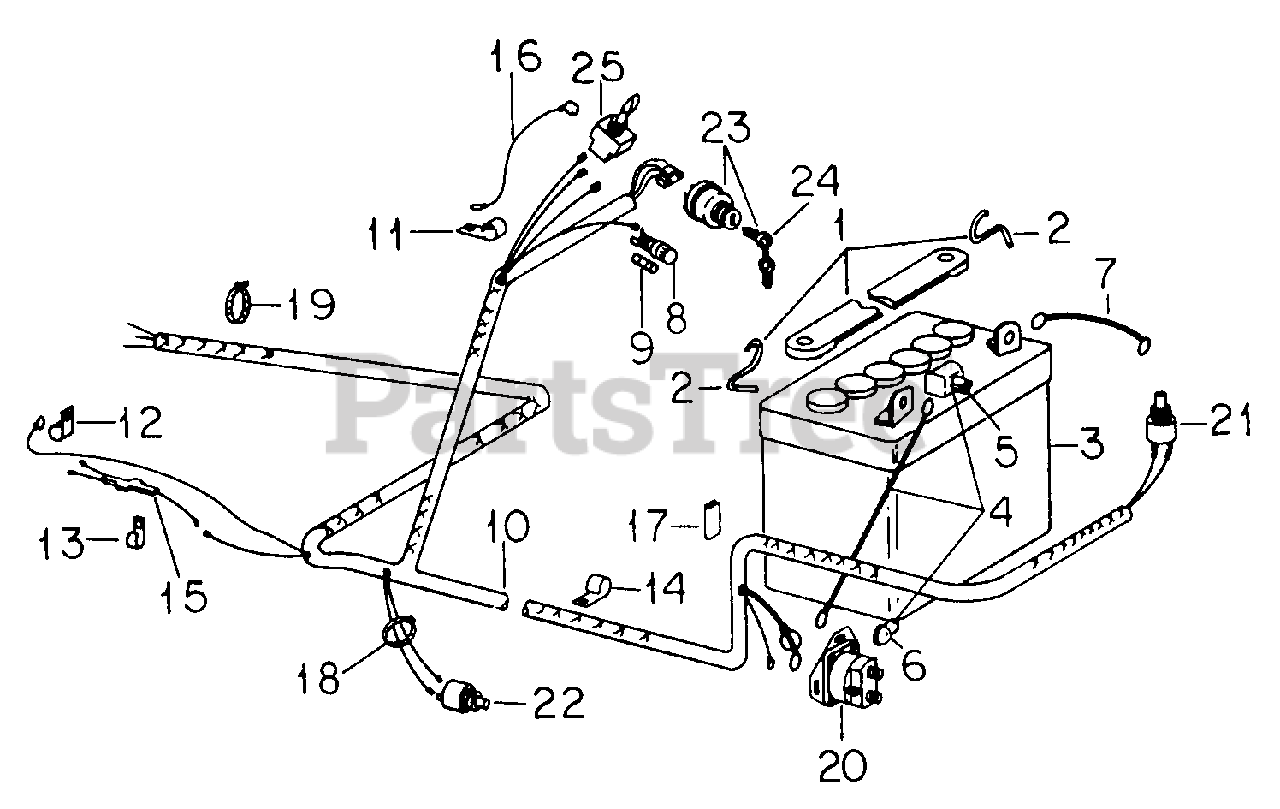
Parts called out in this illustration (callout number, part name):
1	Strap Assy, Battery
2	Hook, Battery Strap
3	Battery, IH Low-Maintenance, 12 Volt
4	Cable, Battery, Positive
5	Cover, Battery Terminal
6	Insulator, Terminal Boot
7	Cable, Battery, Negative Terminal to Ground
8	Holder Assy, Fuse
9	Fuse, 10 Amp
10	Harness Assy, Cable
11	Clip, Cable
12	Clip, Cable, PTO Clutch
13	Clip, Cable, Heat Shield & Frame
14	Clip, Cable, LH Channel at X Member
15	Diode Assy
16	Cable, PTO Switch Ground
17	Not used in this application
18	Strap, Cable Tie
19	Strap, Cable Lock
20	Switch, Magnetic
21	Switch, Neutral Start, Normally Closed
22	Switch, Neutral Start, Normally Open
23	Switch Assy, Battery Ignition Key
24	Key, Ignition Switch
25	Switch, PTO
